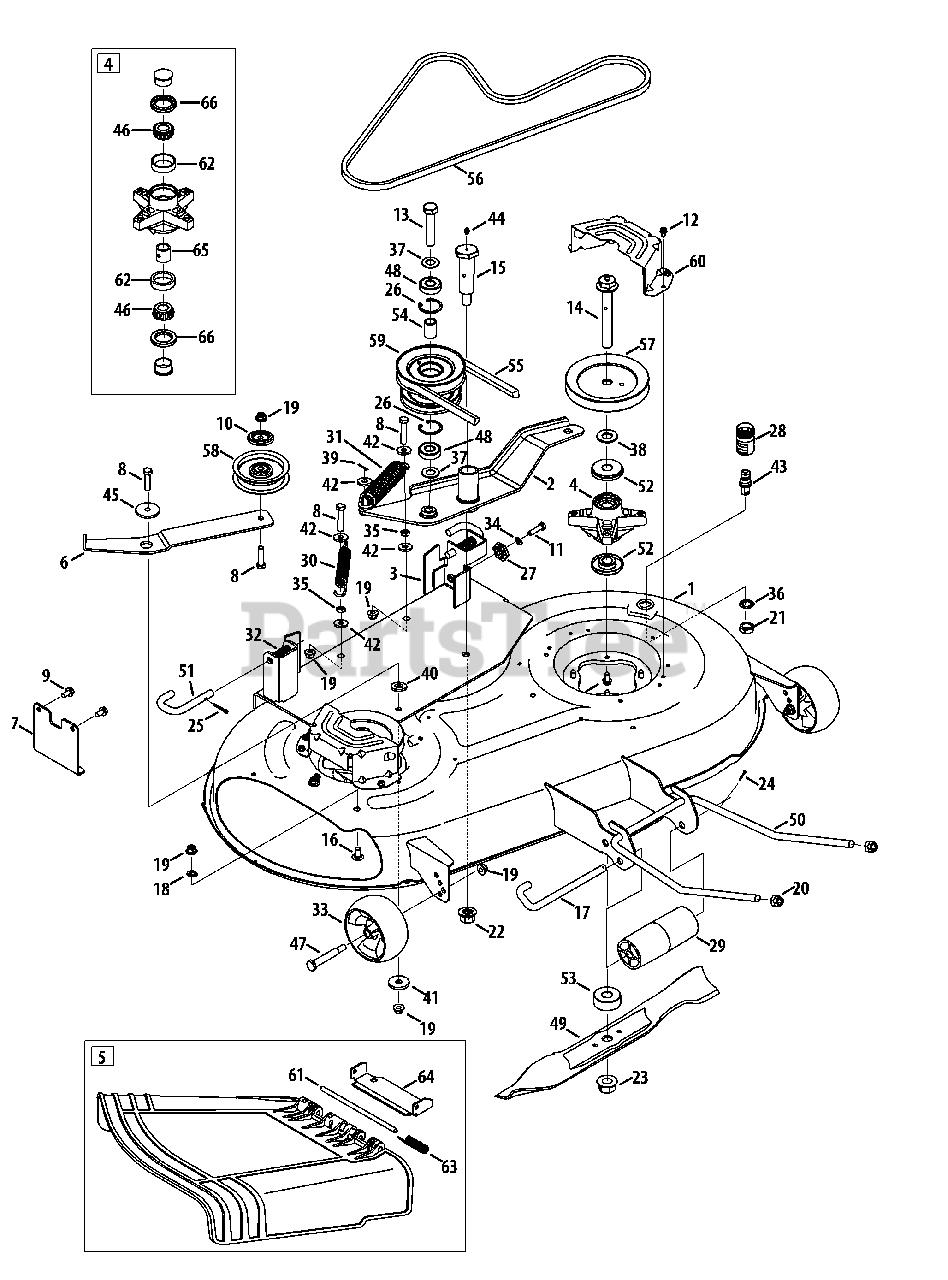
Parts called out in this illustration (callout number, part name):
1	Deck Assembly
3	Hanger Adjustment Bracket
4	Spindle Assembly
5	Chute Assembly
6	Idler Bracket
7	Up-Stop Front Bracket
8	Hex Screw, 3/8 x 16 x 1.75
9	Hex Washer Screw, 5/16-18 x .750
10	Pulley Cap
11	Hex Screw, 5/16-18 x 1.25
12	Hex Washer Screw, 1/4-20 x .500
13	Hex Screw, 5/8-18 x 3.00
14	Spindle Bolt, 3/4-16 x 5.37
15	Shoulder Screw, 1.0 x 3.00
16	Carriage Bolt, 3/8-16 x 1.00
17	Roller Pin, 1/2 x 7.31
18	Push Nut, 3/8
19	Flange Lock Nut, 3/8-16
20	Flex Lock Nut, 1/2-13
21	Hex Nut, 16-1.5
22	Flange Lock Nut, 5/8-18
23	Flange Lock Nut, 3/4-16
24	Cotter Pin, 3/32 x 1.25
25	Cotter Pin, 5/32 x 1.25
26	Retainer Ring
27	Deck Adjustment Gear
28	Water Nozzle Adapter
29	Front Roller
30	Extension Spring, .850 x 6.415
31	Extension Spring, 1.25 x 6.9
32	Compression Spring, .66 x 1.8
33	Deck Wheel, 5.0
34	Lock Washer, 5/16
35	Jam Nut, 3/8-16
36	Lock Washer, 5/8
37	Flat Washer, .65 x 1.25 x .075
38	Flat Washer, .760 x 1.50 x .120
39	Cotter Pin, 3/32 x .75
40	Flat Washer, .385 x 1.0 x .030
41	Flat Washer, .45 x 1.5 x .172
42	Flat Washer, .385 x 1.00 x .135
43	Deck Water Nozzle
44	Drive Lube Fitting, 3/16
45	Shoulder Spacer, .8840 x .190
46	Cone Bearing, .750
47	Shoulder Screw, 1/2 x 2.50
48	Ball Bearing, .625 x 40 x 12
49	2-in-1 Blade, 21.23
50	Front Lift Rod
51	Mower Support Pin
52	Deck Spindle Spacer
53	Spacer, .760 x 2.000 x .790
54	Spacer, .88 x .635 x 1.25
58	Idler Pulley
59	Double Pulley
60	Belt Cover
62	Bearing Cup, .750
63	Torsion Spring, .44 x 2.0
64	Chute Bracket
65	Bearing Spacer, .78 x 1.0 x 1.0425
